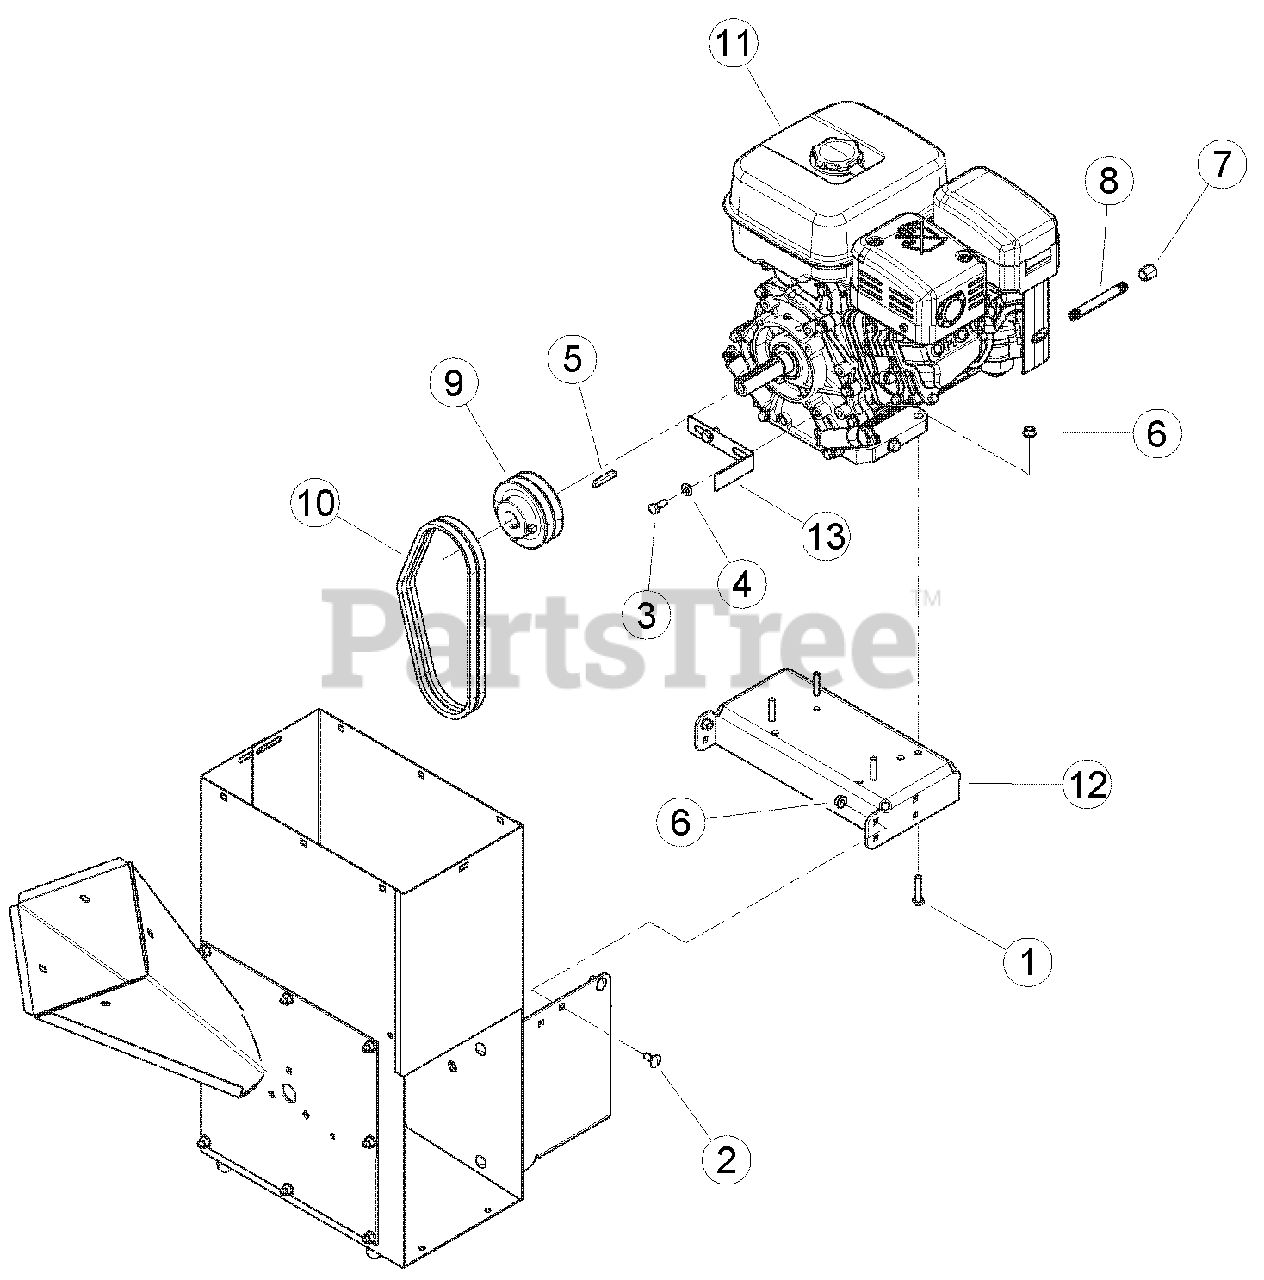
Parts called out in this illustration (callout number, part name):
1	BOLT, 5/16 X 1-1/2 HEX HD GR5 ZP
2	BOLT, 5/16 X 3/4 CRG GR5 NC ZP
3	BOLT, 5/16-24 X 3/4 HEX HD GR5 ZP
4	WASHER, 5/16 SAE FLAT ZP
5	KEY, 1/4 SQUARE X 1-1/2 LONG PLAIN
6	NUT, 5/16 FLANGE TOPLOCK
7	PIPE CAP, 1/4" GALV. HEX HEAD
8	PIPE NIPPLE, 1/4 X 4 GALVANIZED
9	PULLEY, 4X1 2A GROOVE
10	BELTS HAH29.1 EL MATCHED SET
11	ENGINE, SUBARU 265CC EX27 (FOR SERVICE SEE ENGINE OWNER'S MANUAL OR NEAREST AUTHORIZED SUBARU INDUSTRIAL ENGINE DEALER)
11	ENGINE, 342CC B+S HORIZONTAL (FOR SERVICE SEE ENGINE OWNER'S MANUAL OR NEAREST AUTHORIZED BRIGGS & STRATTON ENGINE DEALER)
12	PLATE, ENGINE MOUNTING
13	GUIDE, BELT
